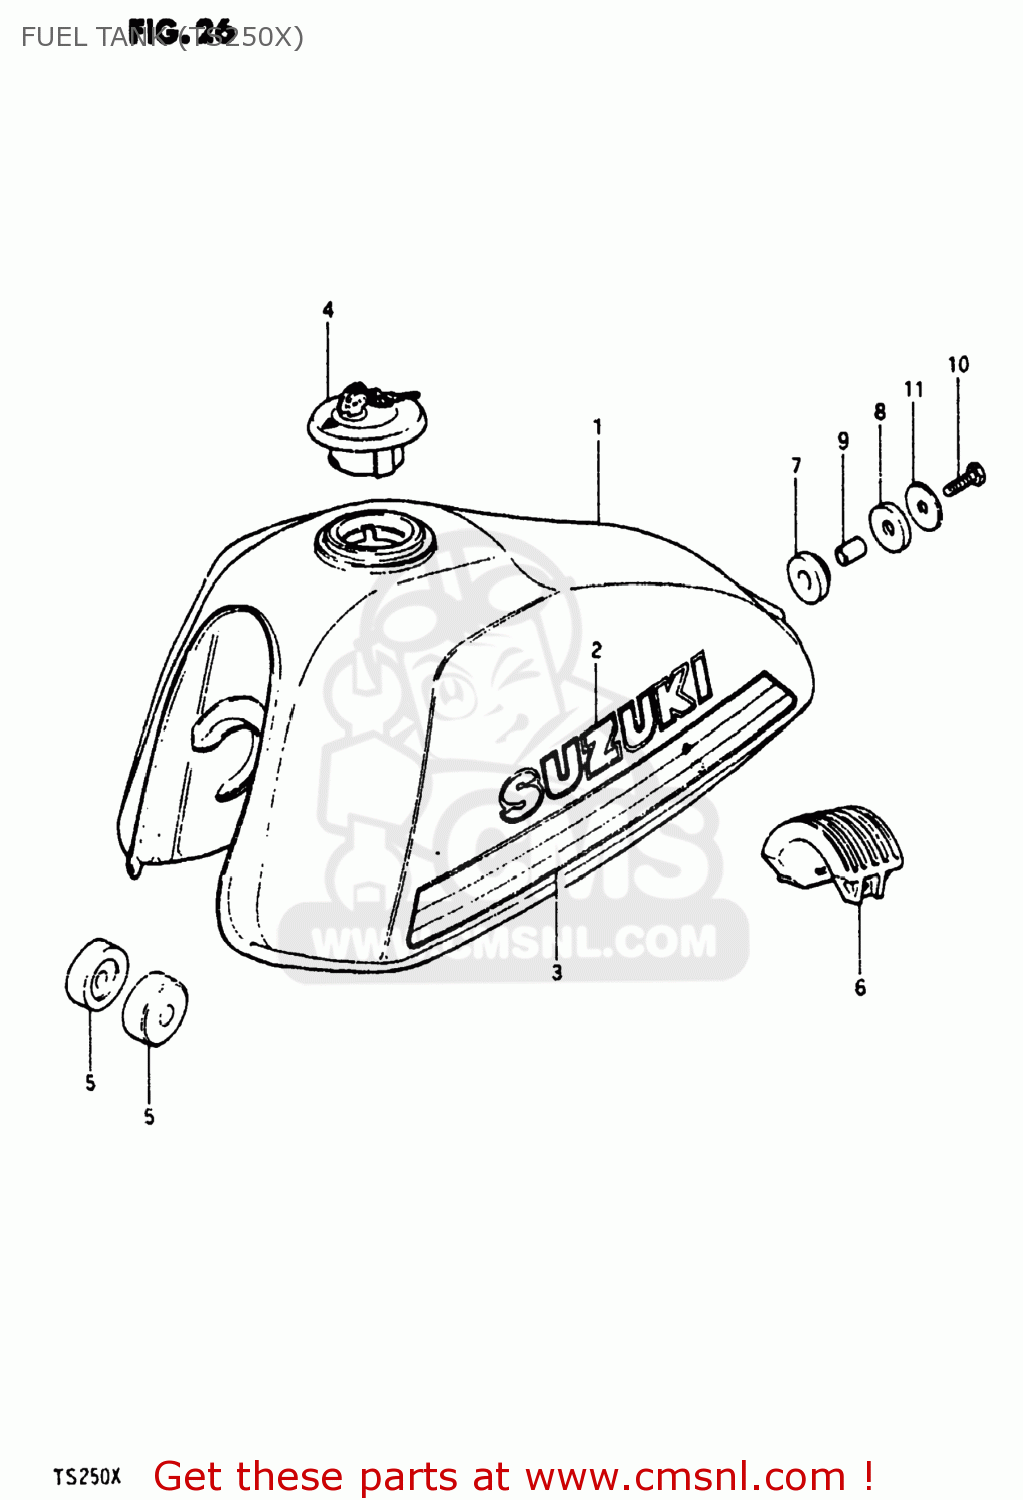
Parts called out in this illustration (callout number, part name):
1	TANK ASSEMBLY,FUEL
2	EMBLEM,FUEL TANK(WHITE)
3	TAPE SET,FUEL TANK STRIPE
4	CAP SET,FUEL TANK
5	CUSHION
6	CUSHION,FUEL TANK
7	CUSHION
8	CUSHION
9	SPACER (8.2X12X17)
10	BOLT (8X30)
11	WASHER (8.5X29X1.6)
